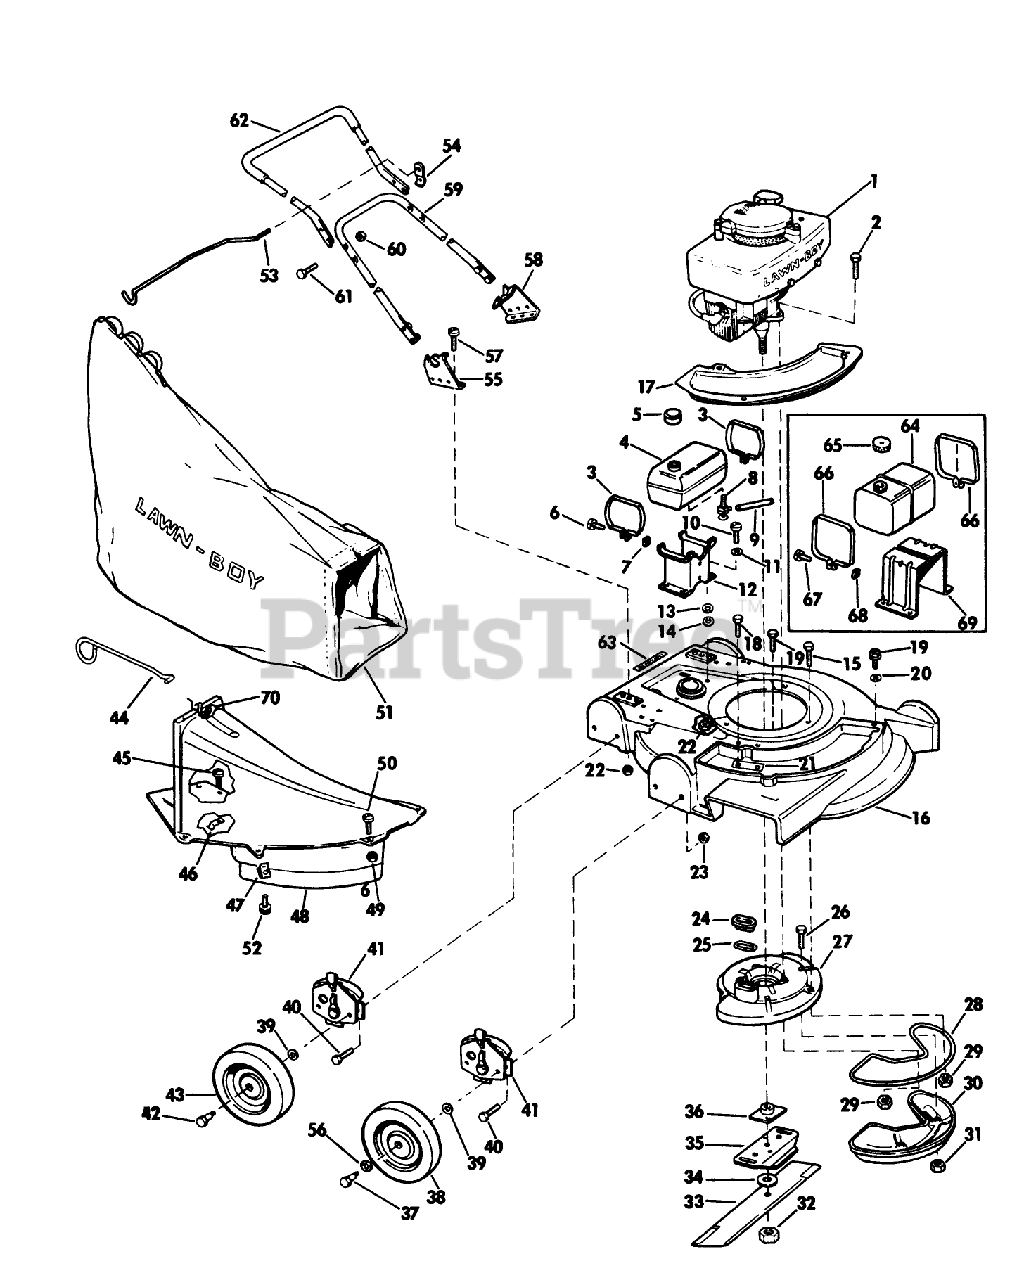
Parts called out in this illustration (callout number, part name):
7	Nut
8	VALVE&SCREEN SM
14	WASHER
15	SCREW
23	NUT
24	SLEEVE
25	GASKET S
29	NUT
31	LOCKNUT E
32	NUT-BLADE
34	WASHER
36	PLATE AND COLLAR ASM
37	BOLT WHEEL
39	WASHER WROUGHT
41	Height Adjustment Assy.
42	BOLT-SHOULDER
45	Screw
47	SPEED NUT ARDEN
48	Chute Skirt Assembly (Includes Hardware)
49	NUT S
51	89802 LB WHOLE GOODS
53	ROD & CLIP
56	Washer
57	SCREW S
59	HANDLE
60	STOP NUT
62	Handle Grip Assy. Top
68	Nut
